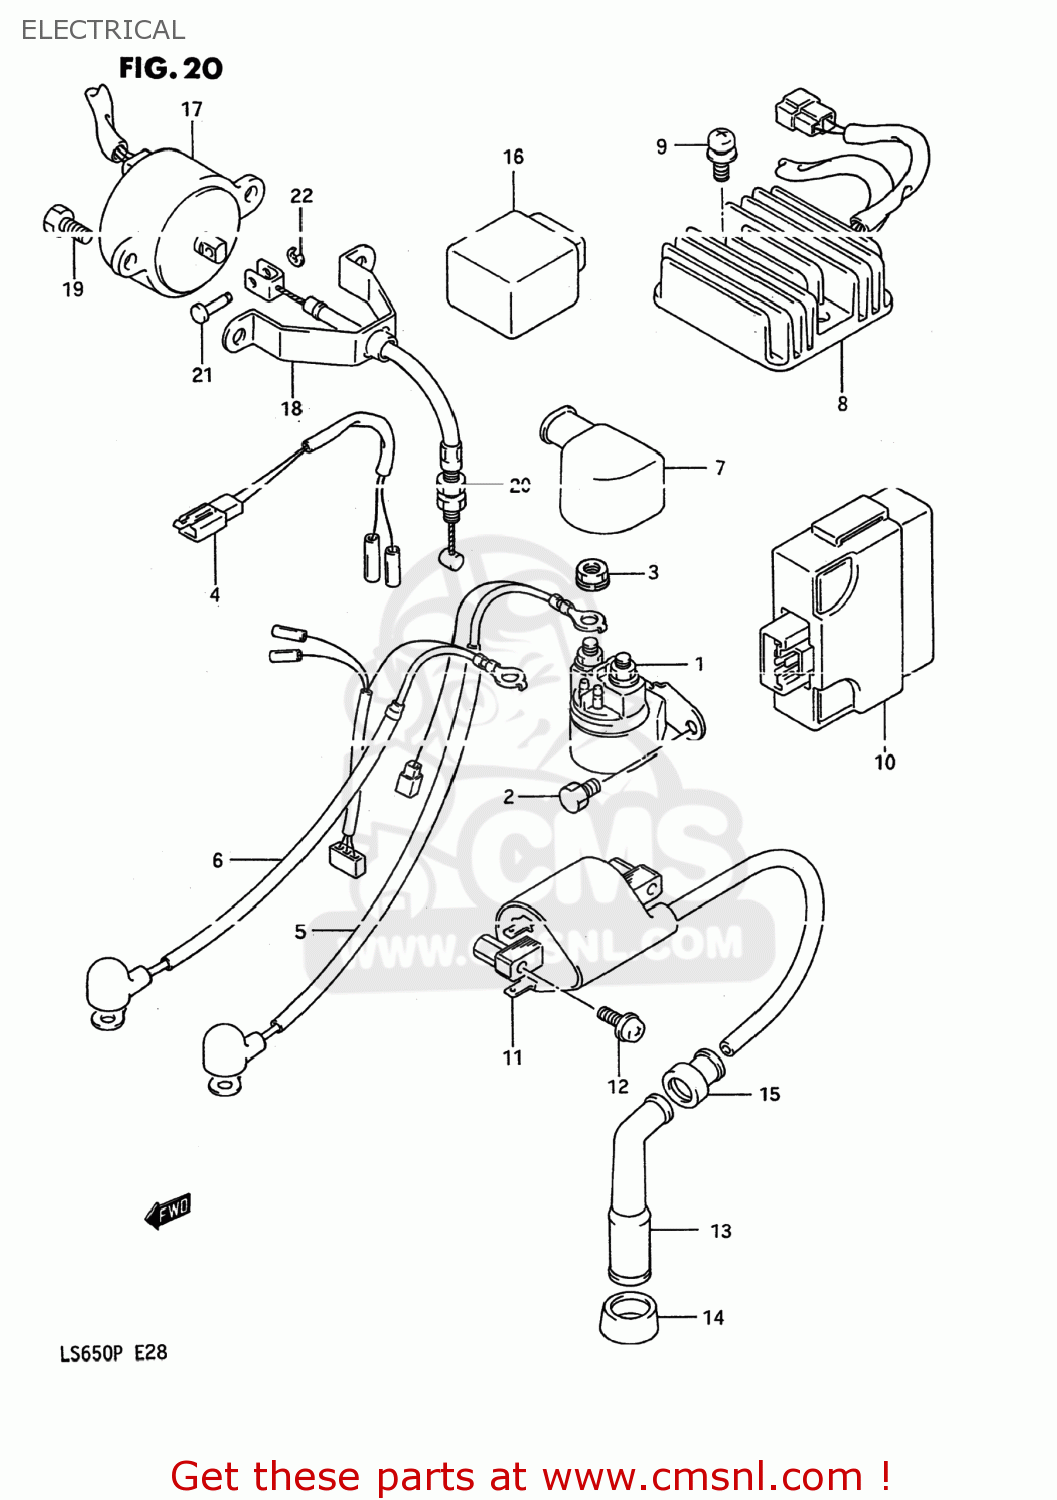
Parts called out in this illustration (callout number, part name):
1	RELAY ASSY,STARTING MOTOR
2	BOLT
3	NUT
4	WIRE,STARTER RELAY LEAD
5	WIRE,STARTER MOTOR
6	WIRE,STARTER MOTOR
7	CAP,STARTER RELAY TERMINAL
8	RECTIFIER ASSY
9	SCREW
10	IGNITOR ASSY
11	COIL ASSY,IGNITION
12	SCREW
13	CAP ASSY,SPARK PLUG
14	SEAL,SPARK PLUG CAP
15	SEAL,HIGH TENSION CORD
16	CONTROL UNIT,DECOMP
17	SOLENOID ASSY,DECOMP
18	BRACKET,DECOMP SOLENOID
19	BOLT 6X16
20	CABLE ASSEMBLY,DECOMPRESSION
21	PIN(4X12.5)
22	E RING
